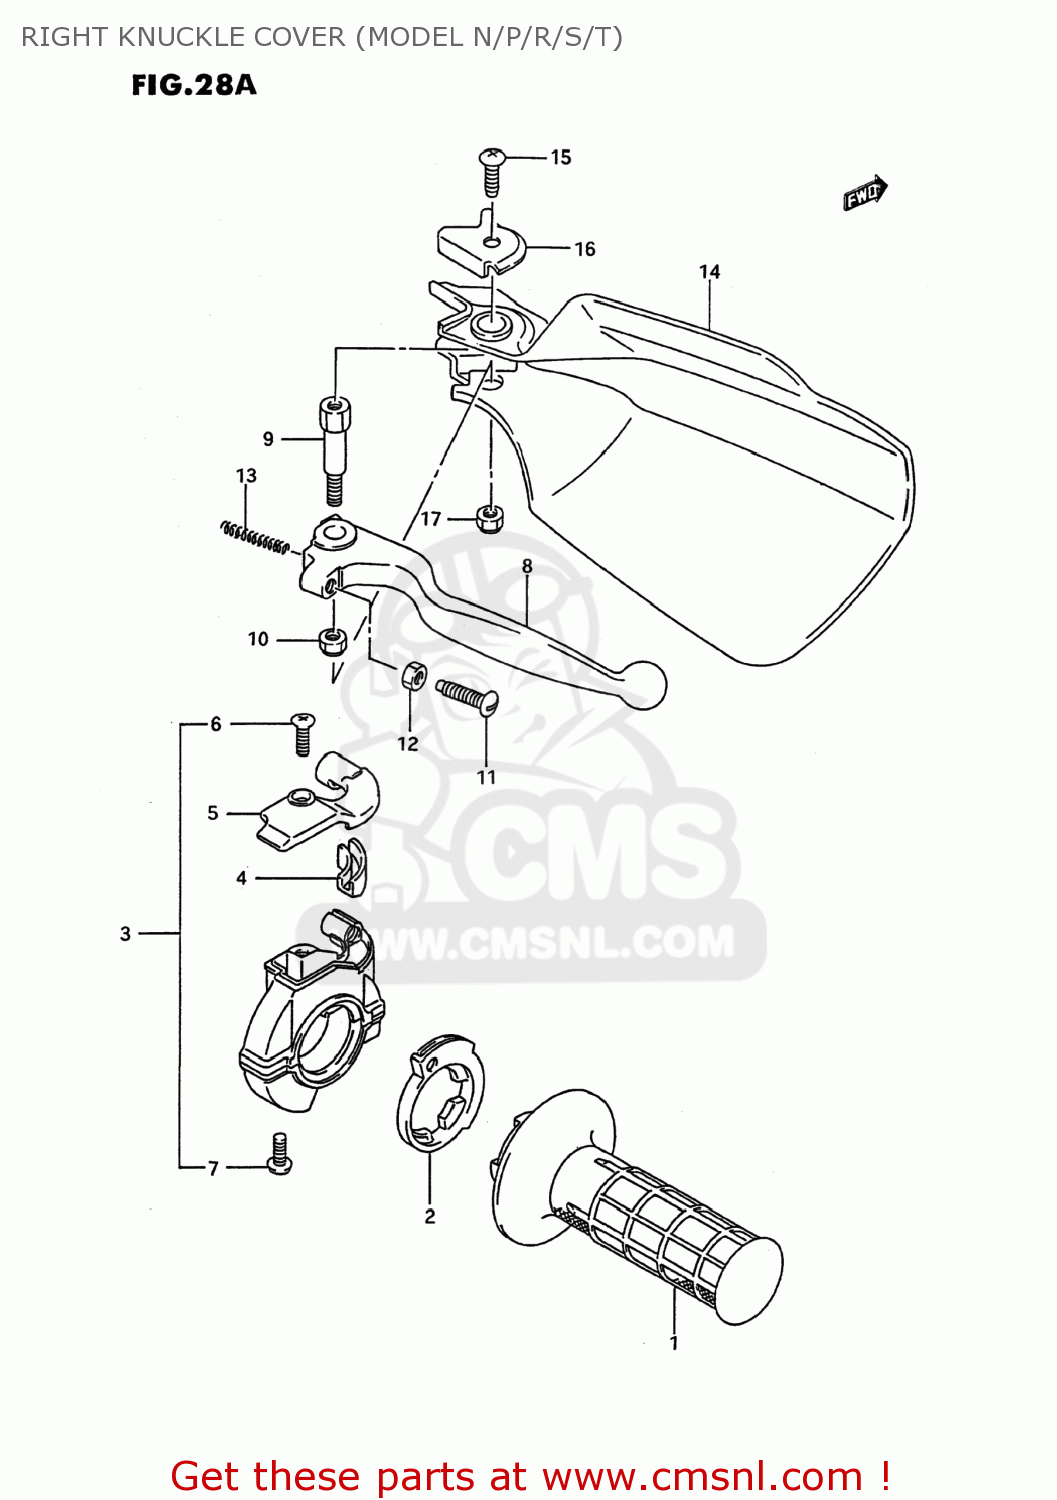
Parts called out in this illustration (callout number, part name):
1	GRIP,THROTTLE
2	ROTOR,THROTTLE GRIP
3	CASE ASSY,THROTTLE
4	GUIDE PIECE,THROTTLE
5	COVER,THROTTLE CASE
6	SCREW,UPPER
7	SCREW
8	LEVER,BRAKE
9	BOLT,BRAKE LEVER PIVOT
10	NUT 6MM
11	BOLT,ADJUST
12	NUT ,5MM
13	SPRING,RETURN
14	COVER,KNUCKLE,R
15	SCREW
16	PLATE,KNUCKLE COVER,R UPR
17	NUT 6MM
